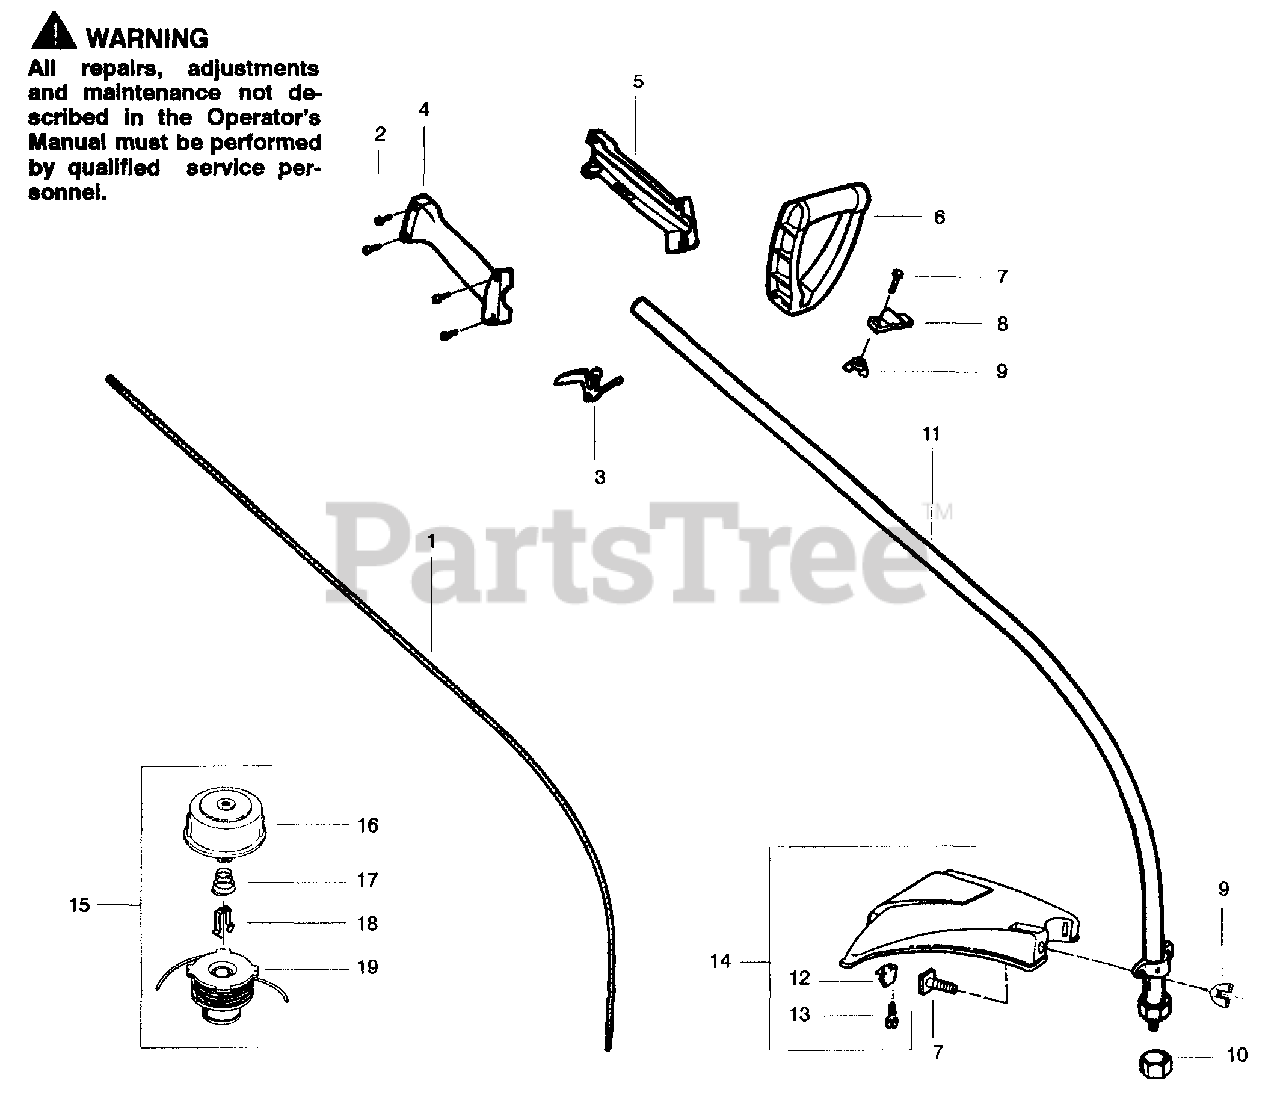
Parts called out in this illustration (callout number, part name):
1	Drive Shaft
2	Screw - Throttle Hsg.
4	Throttle Hsg. (Right)
5	Throttle Hsg. (Left)
6	Handle Ass'y.
7	Bolt - Handle/Shield
8	Clamp - Assist Handle
9	Wingnut
10	Dust Cup
11	Drive Shaft Hsg. Ass'y.
12	Line Limiter
13	Screw - Line Limiter
14	Shield Kit Ass'y.
15	Cutting Head Ass'y.
16	Hub Ass'y.
17	Spring - Return
18	Retainer - Spool
19	Spool w/Line
